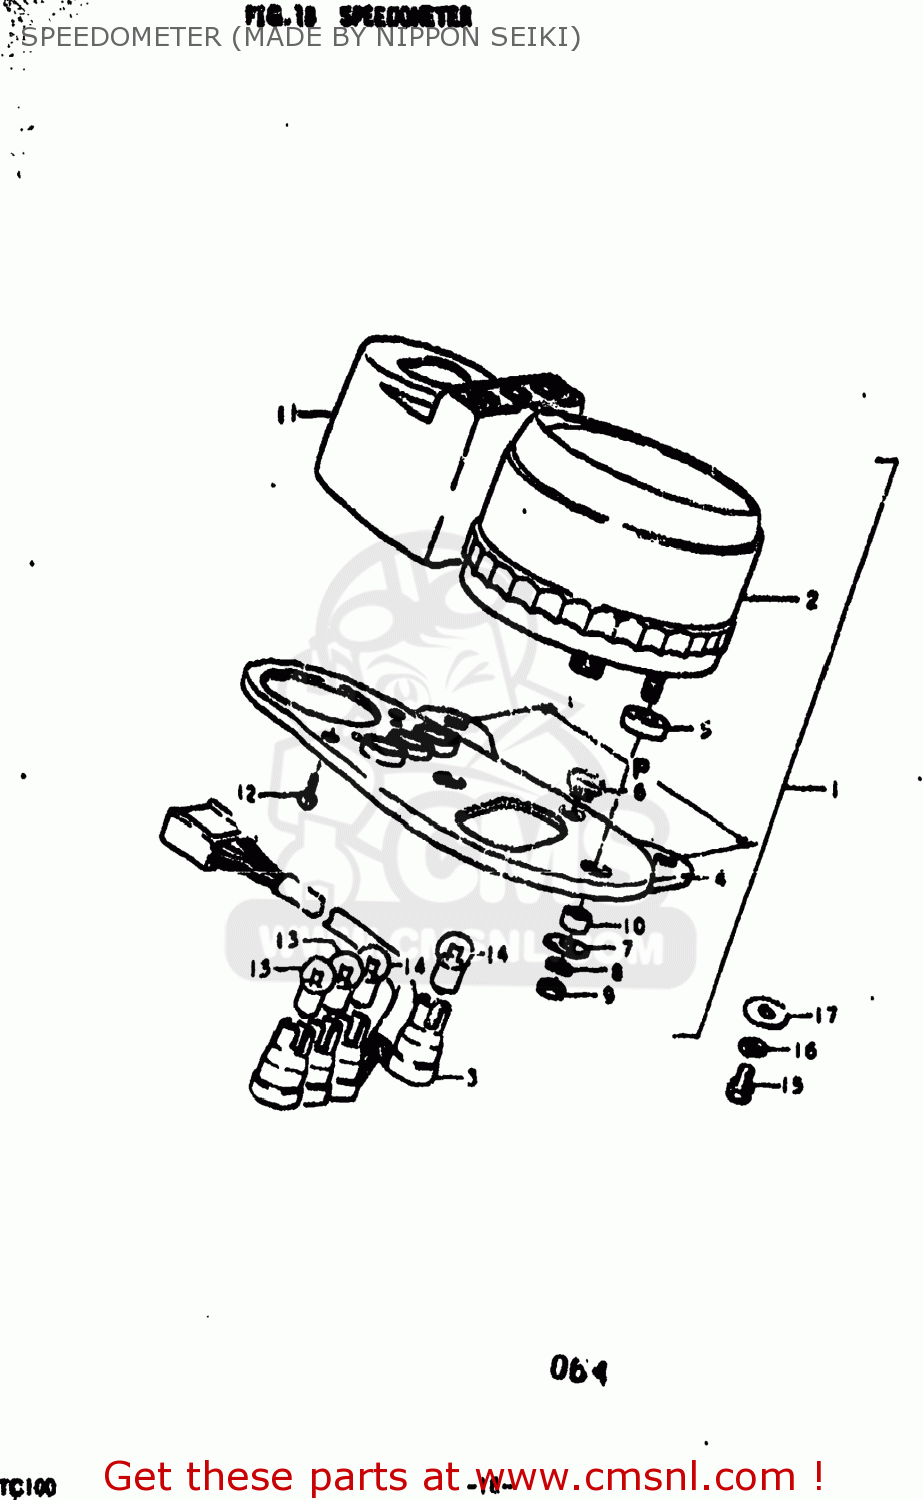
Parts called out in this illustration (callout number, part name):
1	SPEEDOMETER ASSEMBLY
2	SPEEDOMETER ASSEMBLY
3	SOCKET,METER
4	BRACKET,METER
5	CUSHION,METER NO.1
6	CUSHION,METER
7	WASHER
8	LOCK WASHER
9	NUT
10	SPACER,METER
11	CASE,PILOT BULB
12	SCREW
13	BULB(6V1.7W,STANLEY,A61A)
14	BULB(6V/3W)
15	BOLT
16	LOCK WASHER
17	WASHER 6MM
